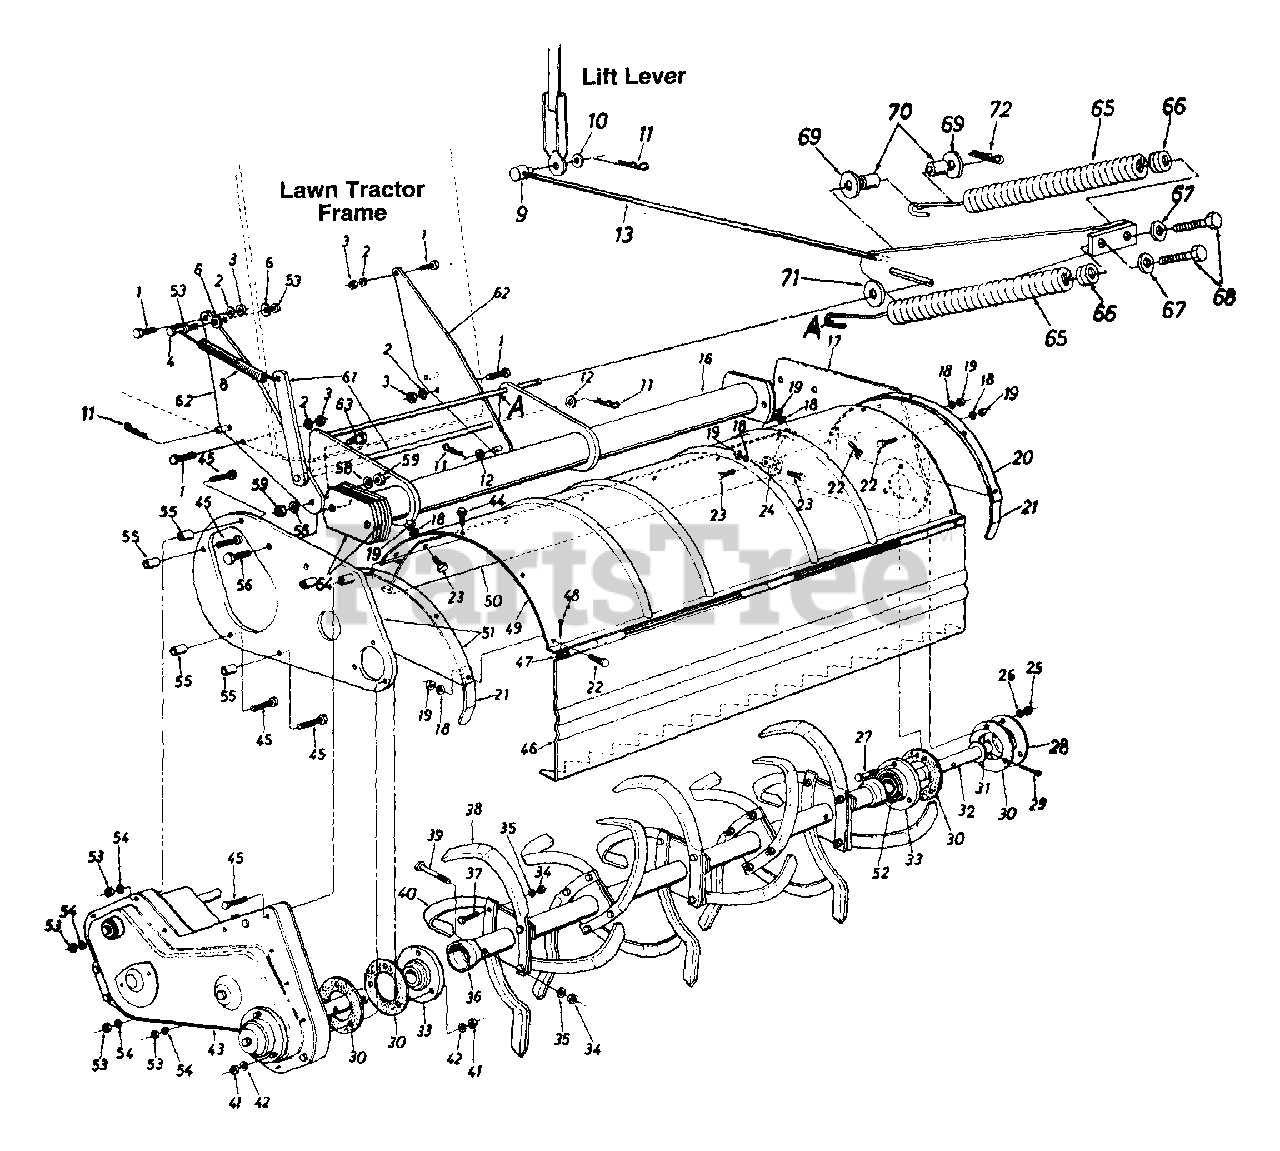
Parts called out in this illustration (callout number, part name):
1	Hex Bolt 3/8-24 x .88" Lg.
2	L-Wash. 3/8" I.D.- H.D.
3	Hex Nut 3/8-24 Thd.
4	Hex Bolt 1/4-20 x 1.25" Lg.
6	Bell-Wash. 1/4" I.D.
8	Ext. Spring 7.75" Lg.
9	Adjustment Ferrule 1/2-13 Thd.
10	Fl-Wash. .64" I.D. x 1.24" O.D. x .06"
11	Intern. Cotter Pin 1/2" Dia.
12	Fl-Wash. .51" I.D. x 1.0" O.D. x .06"
13	Lift Bracket Ass'y.
14	Comp. Spring 1.5" O.D. x 15" Lg.
15	Fl-Wash. .51" I.D. x 1.5" O.D. x .075"
16	Pivot Bracket Assembly
19	Hex Nut 5/16-24 Thd.
23	Hex Bolt 5/16-24 x .62" Lg.
24	Chute Pivot Bracket
25	Hex L-Nut 5/16-18 Thd.
27	Hex Bolt 5/16-18 x 1" Lg. (Grade 5)
30	Gasket for Brg. Housing
31	Fl-Wash. 1.25" I.D. x 2.0" O.D. x .06"
32	Tine Shaft 1.25" Dia. x 6.25" Lg.
33	Bearing Housing w/Bearing
38	Tine 14" x 5/16"
39	Hex Bolt 3/8-24 x 2.25" Lg.
40	Tine 14" x 5/16"
43	Chain Case Ass'y. Comp.
44	Hex TT-Tap Scr. 5/16-18 x .62" Lg.
45	Hex Bolt 1/4-20 x 2.75" Lg.
48	Cotter Pin 1/8" Dia. x 1" Lg.
53	Hex Nut 1/4-20 Thd.
54	L-Wash. 1/4" I.D.
55	Spacer .28" I.D. x .62" O.D. x .9" Lg.
56	Hex Bolt 1/2-20 x 1.5" Lg.
58	L-Wash. 1/2" I.D.
59	Hex Nut 1/2-20 Thd.
61	Idler Brkt. Support Arm Ass'y.
62	Pivot Brkt. Support
63	Shoulder Bolt
64	Support Plate
65	Helper Spring
66	Spring Insert
67	Fl-Wash. .34" I.D. x .68" O.D.
68	Hex Bolt 5/16-18 x 3.25" Lg.
69	Fl-Wash. .51" I.D. x 1.5" O.D.
70	Split Spacer .505" I.D. x .57" Lg.
71	Fl-Wash. .531" I.D. x 1.25" O.D.
72	Internal Cotter Pin 1/2" Dia.
